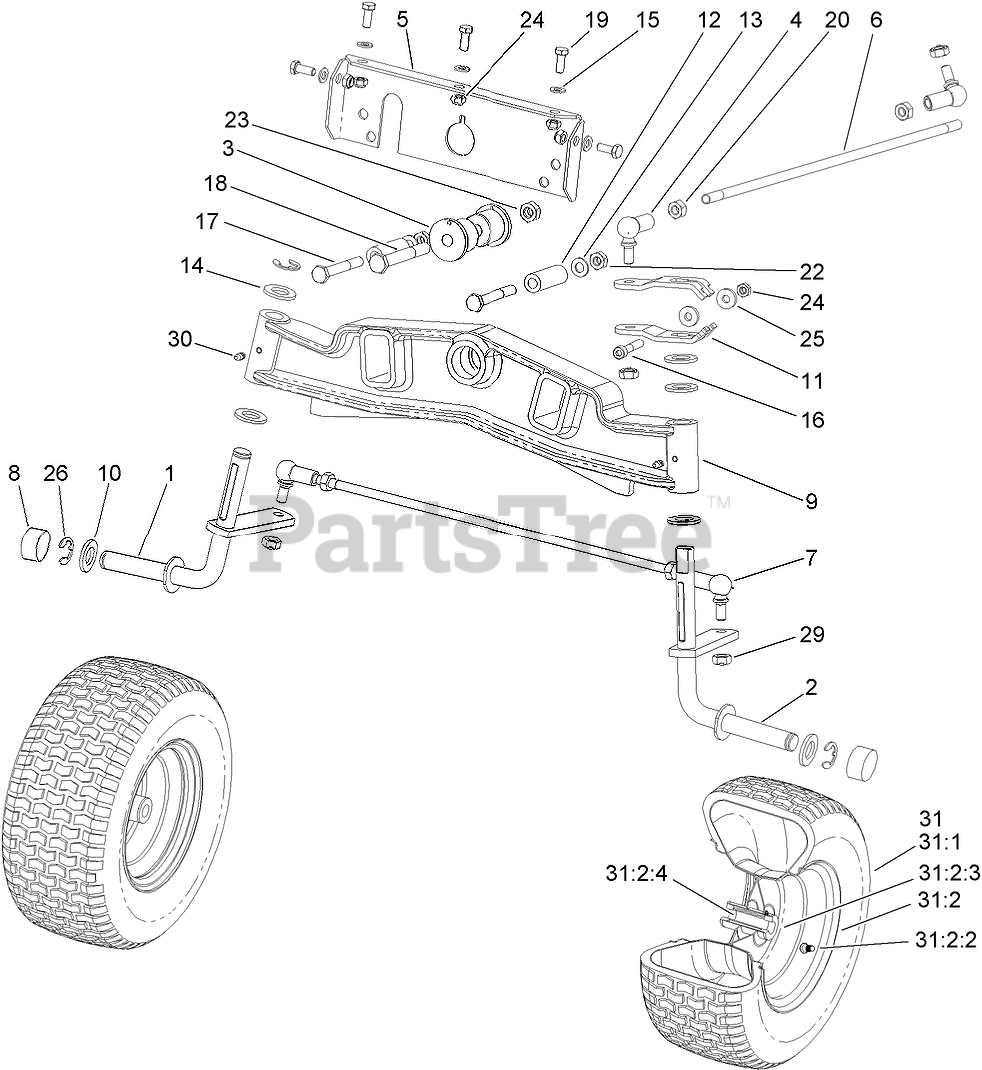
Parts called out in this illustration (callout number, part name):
1	SPINDLE-FRONT, RH
2	SPINDLE-FRONT, LH
3	BUSHING-AXLE, FRONT
4	JOINT-BALL, ANGLE
5	PLATE-AXLE
6	LINK-DRAG
7	ROD-TIE, FRONT AXLE
8	CAP-HUB
9	AXLE-FRONT
10	WASHER
11	LEVER-SPINDLE, STEERING
12	SPACER
13	WASHER-FLAT
14	WASHER-FLAT
15	WASHER-PLAIN
17	SCREW-HH
18	SCREW-HH
19	SCREW-HH
20	NUT-HEX
22	NUT-LOCK
23	NUT-LOCK, HEX NI
24	NUT-LOCK, NI
25	Washer-Flat
26	CLIP-SPRING
29	NUT-LOCK, NI
30	FITTING-GREASE
31	WHEEL ASM
31:2	WHEEL ASM
31:2:2	Valve-Tire
31:2:3	BEARING-WHEEL
31:2:4	Spacer-Wheel
